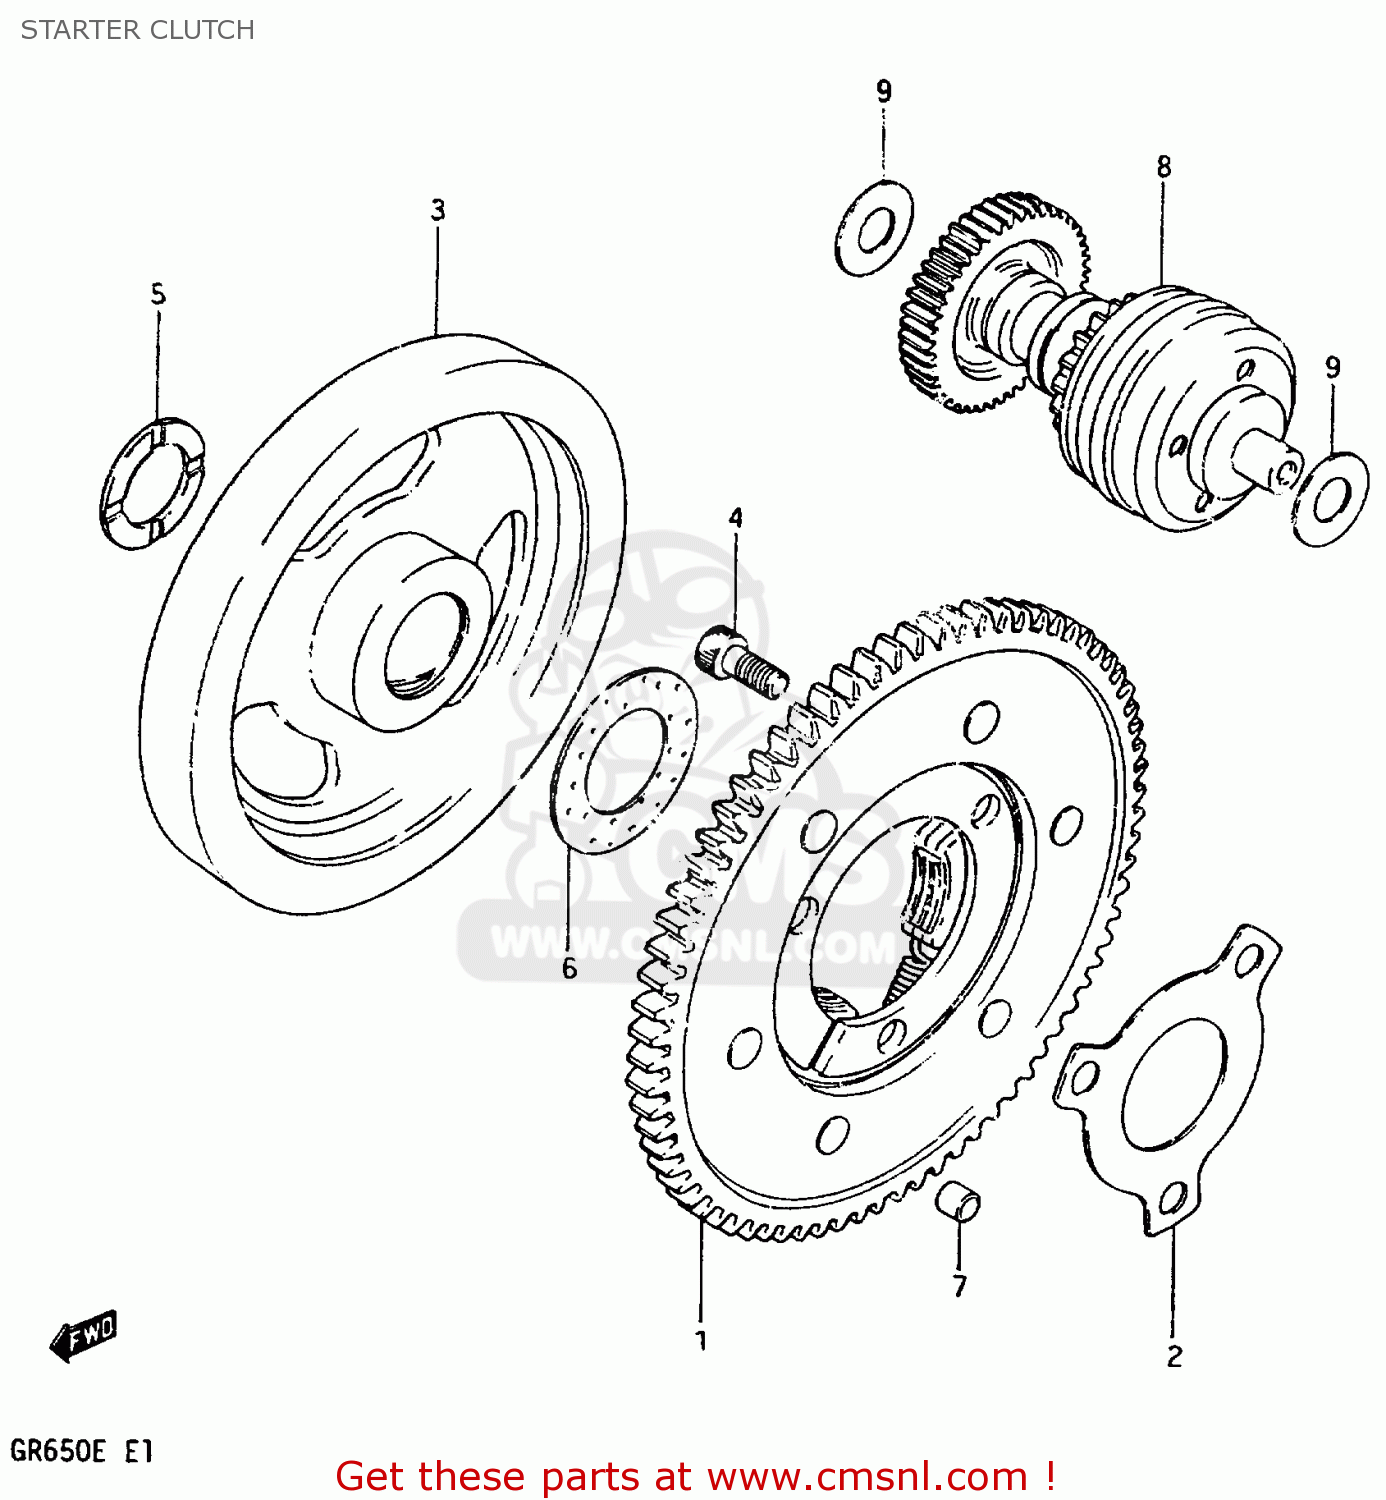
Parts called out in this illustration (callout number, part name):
1	GEAR,STARTER
2	SHIM
3	FLYWHEEL,CLUTCH
4	BOLT
5	WASHER(27X40X2.5)
6	WASHER (27X48X1)
7	PIN
8	PINION GEAR ASSEMBLY,STARTER
9	SHIM
